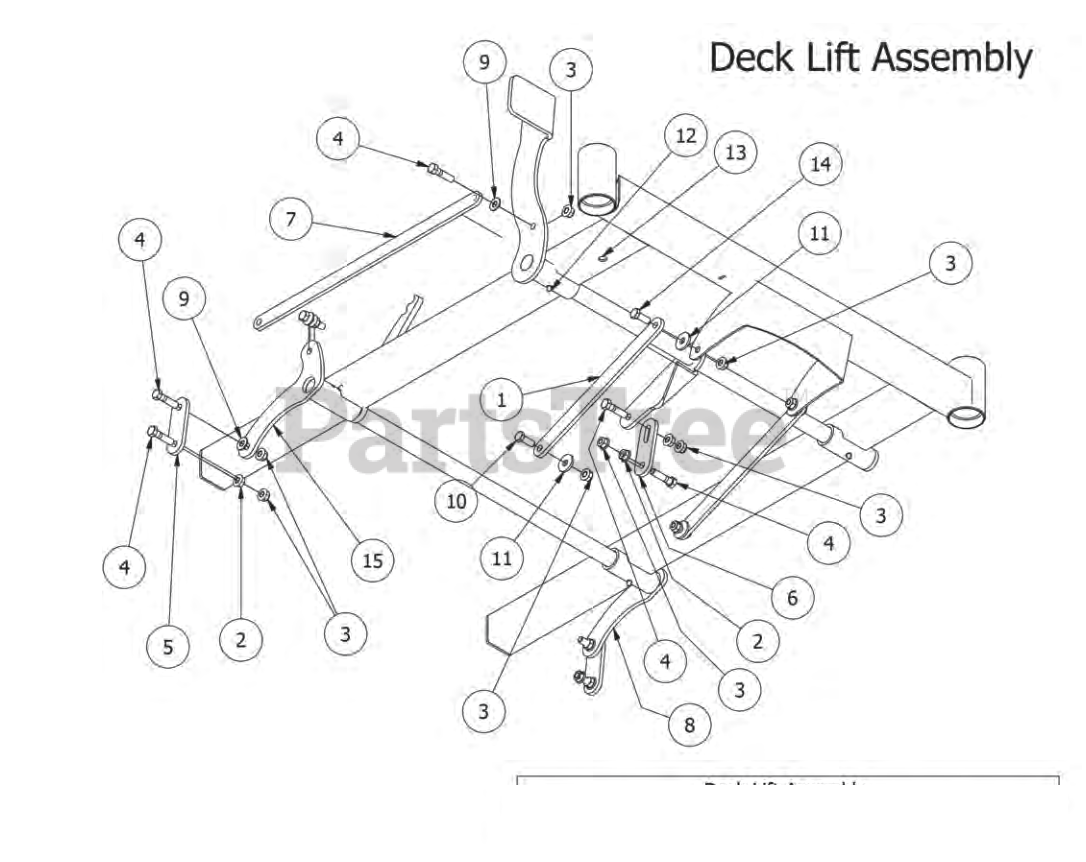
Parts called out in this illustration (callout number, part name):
1	MZ Front Arm
2	3/8" Flange Nut
3	3/8" Nylock Flange Nut
4	3/8" x 1 1/2" Hex Bolt
5	48 Deck Spacer MZ
6	48 Deck Spacer MZ (Front)
7	MZ Deck Linkage Rod
8	MZ Deck Pivot Lever 2
9	360 ID Plastic Washer
10	3/8" x 1" Hex Bolt
11	.390 ID Plastic Washer
12	1/4" Press in Grease Fitting
13	5/8 Round insert
14	3/8-16 x 1-1/4 GR 5 Hex Bolt
15	MZ Deck Pivot Lever
